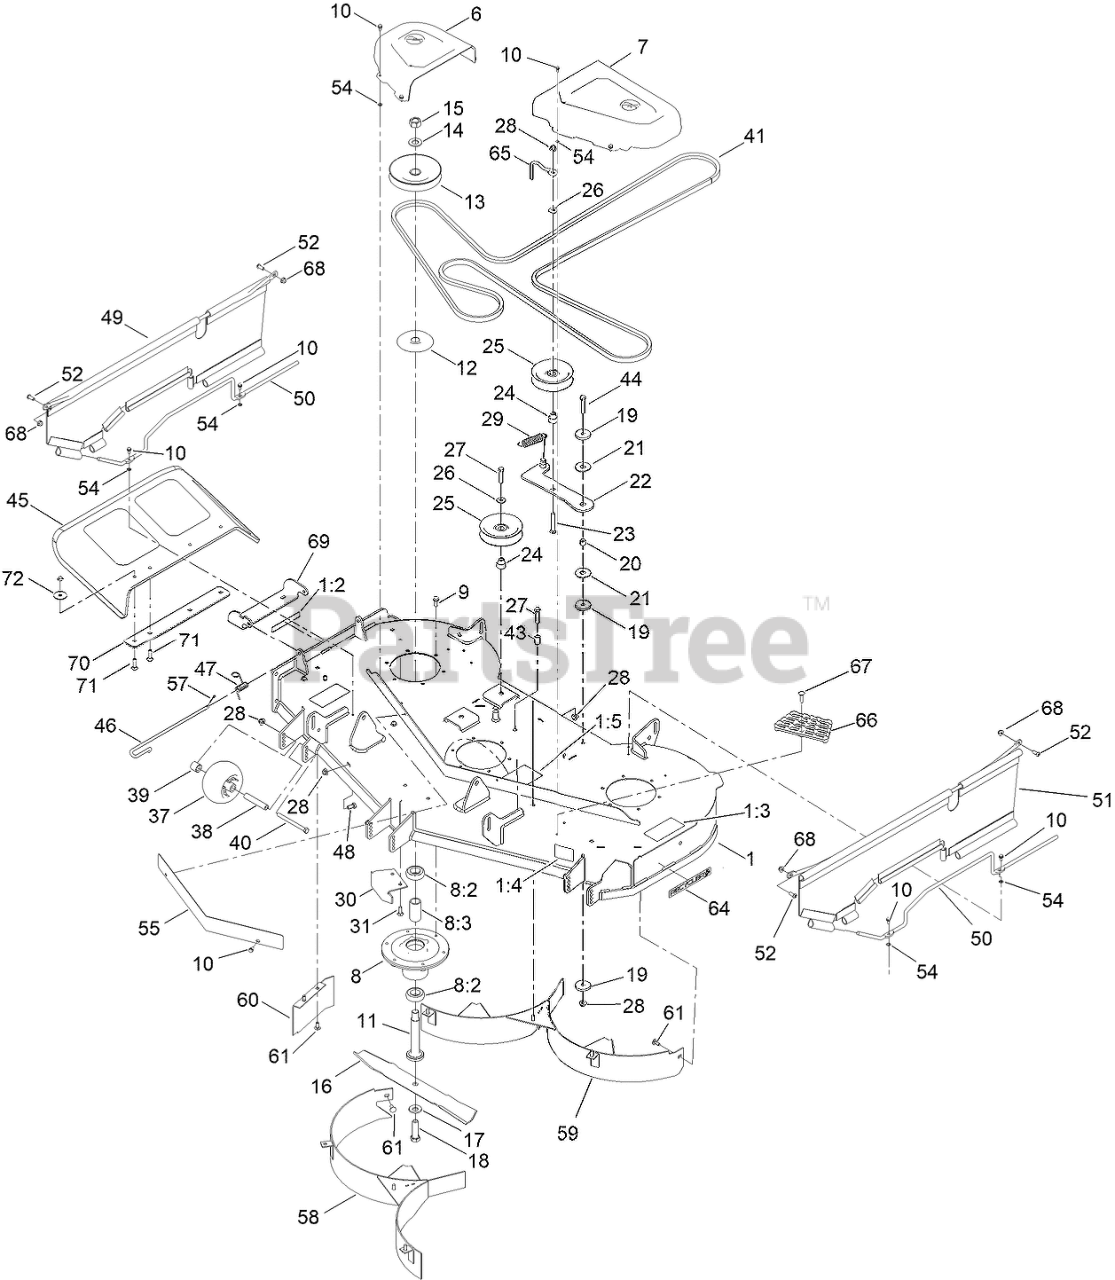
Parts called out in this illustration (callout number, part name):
1	54in DECK ASM
1:2	DECAL-DANGER
1:3	DECAL-DANGER, DECK
1:4	DECAL-SCALP, ANTI
1:5	DECAL-ROUTING, BELT
6	COVER-BELT, RH
7	COVER-BELT, LH
8	SPINDLE ASM
8:2	BEARING-BALL
8:3	SPACER-BEARING
9	SCREW-TAPTITE
10	SCREW-HWH
11	SHAFT-SPINDLE
12	SHIELD-BEARING
13	PULLEY
14	WASHER
15	NUT-HEX
16	BLADE-MULCH, 18.75 INCH
17	WASHER-BELLEVILLE
18	SCREW-BLADE
19	WASHER-PLAIN
20	SPACER
21	WASHER-FRICTION, COMPOSITE
22	IDLER ARM ASM
23	SCREW-CARR
24	BUSHING-IDLER
25	PULLEY-IDLER, FLAT
26	WASHER-HARDENED
27	SCREW-HH
28	NUT-HF, NI
29	SPRING-EXTENSION
30	BAFFLE-CUTOFF
31	SCREW-CARR
37	ROLLER-SCALP, ANTI
38	TUBE-SPANNER
39	SPACER-AXLE, REAR
40	SCREW-HH
41	V-BELT
43	SPACER-FENDER
44	HHCS 3/8-16 X 2, GR5, CZ
45	DEFLECTOR
46	PIN-CHUTE
47	SPRING-TORSION
48	SCREW-HH
49	ROD SUPPORT, UPPER
50	ROD SUPPORT, LOWER
51	SIDE GUARD ASM
52	SCREW-HSBH
54	NUT-RETAINING
55	SHIELD-FRONT
57	PIN-COTTER
58	BAFFLE-RECYCLER
59	BAFFLE-RECYCLER, LH
60	GUARD-BAFFLE
61	BOLT-CARR
64	DECAL-RECYCLER
65	GUIDE-BELT, IDLER
66	STEP-DECK
67	BOLT-CARRIAGE
68	NUT-HF, NI
69	BRACKET-DEFLECTOR, UPPER
70	PLATE-DEFLECTOR
71	BOLT-CARRIAGE
72	WASHER-FLAT
